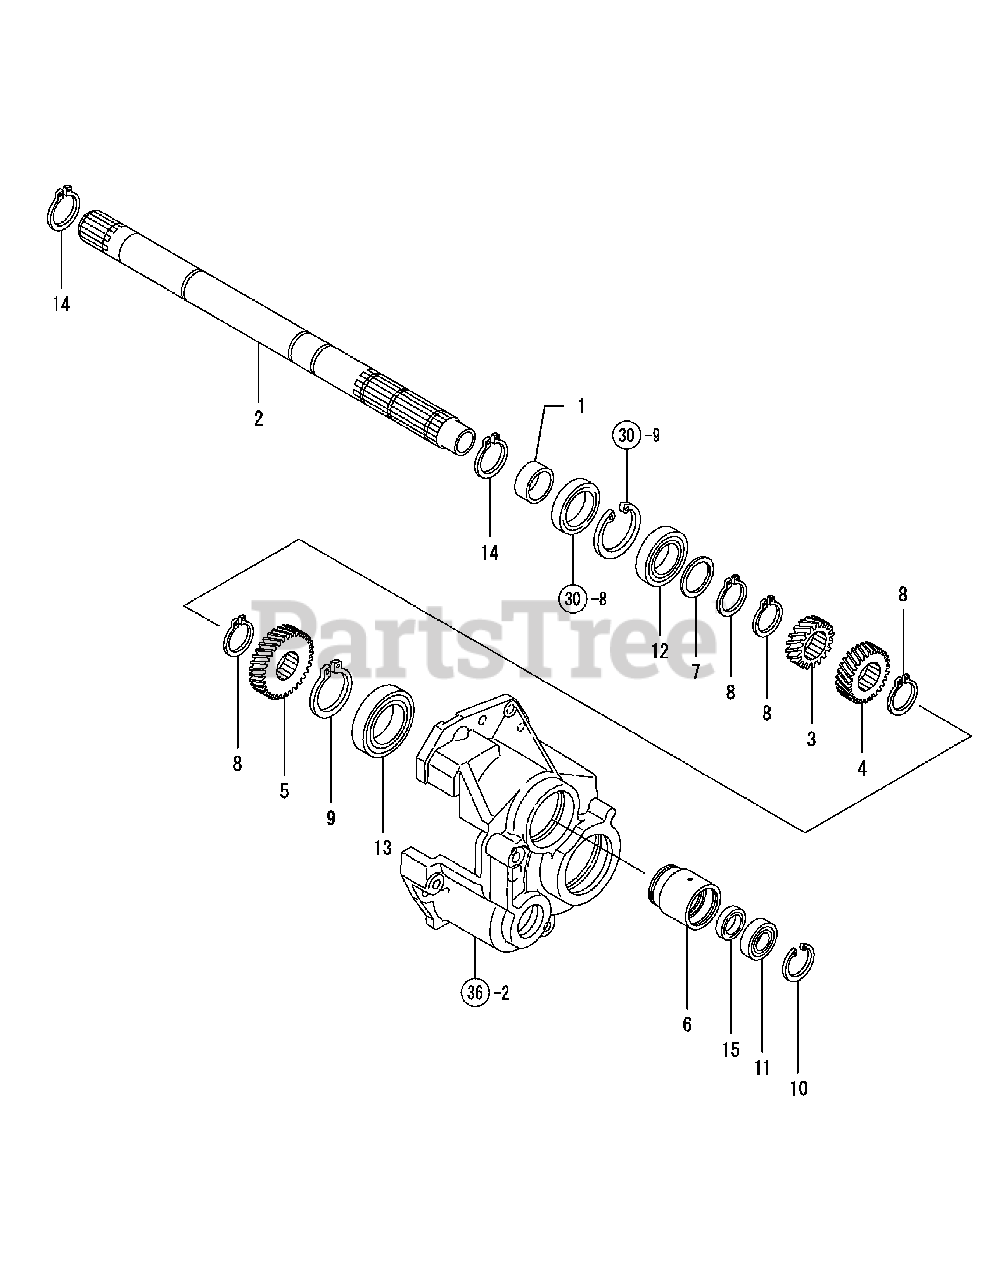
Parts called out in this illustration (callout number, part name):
1	SEAL COLLAR 35X40X17
7	SPACER 35X45X2
11	BALL BEARING #6004
15	SEAL TC22 35 08, OIL
